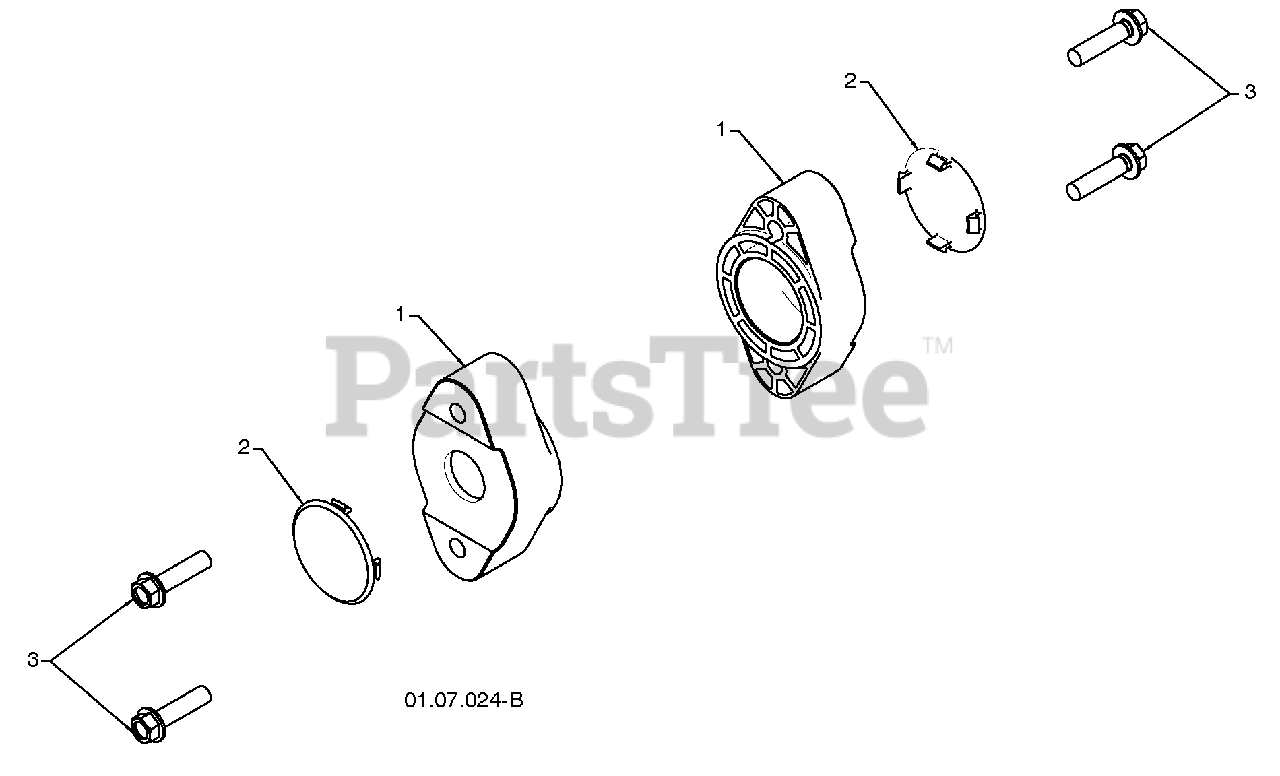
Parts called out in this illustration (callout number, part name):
1	AUGER BEARING
2	BEARING PLUG
3	SCREW 5/16-18 X 1.00
